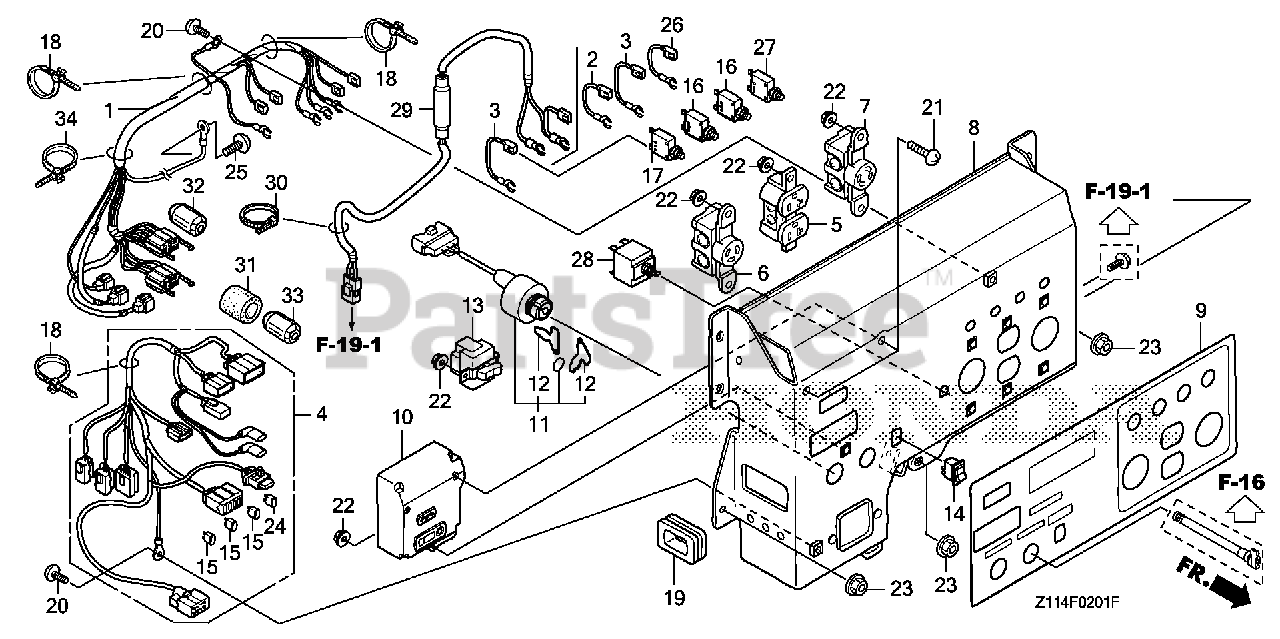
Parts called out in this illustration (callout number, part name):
1	WIRE HARNESS ASSY., MAIN
2	SUB-WIRE ASSY. (A)
3	SUB-WIRE ASSY. (D)
4	WIRE HARNESS ASSY., CONTROL
5	RECEPTACLE (20A/125V) (MATSUSHITA)
6	RECEPTACLE (3-PRONG) (30A/125V)
7	RECEPTACLE (30A/125-250V)
8	PANEL, CONTROL
9	MARK, PANEL (EM-A)
10	CONTROL UNIT ASSY., GENERATOR
11	SWITCH ASSY., COMBINATION
12	KEY
13	SWITCH ASSY., VOLT CHANGE
14	SWITCH, AUTO-THROTTLE
15	FUSE, BLADE (1A)
16	PROTECTOR, CIRCUIT (20A) (WHITE)(TYCO)
17	PROTECTOR, CIRCUIT (30A) (WHITE)
18	STRAP, CABLE (105MM) *NH1* (Honda Code 1685536). (BLACK)
19	GROMMET, CONTROL HARNESS
20	SCREW, PAN (5X8)
21	SCREW, PAN (5X12)
22	NUT, FLANGE (4MM)
23	NUT, FLANGE (6MM)
24	FUSE, BLADE (15A)
26	SUB-WIRE ASSY. (A)
27	PROTECTOR, CIRCUIT (30A) (WHITE)
34	STRAP, CABLE (105MM) *NH1* (Honda Code 1685536). (BLACK)
